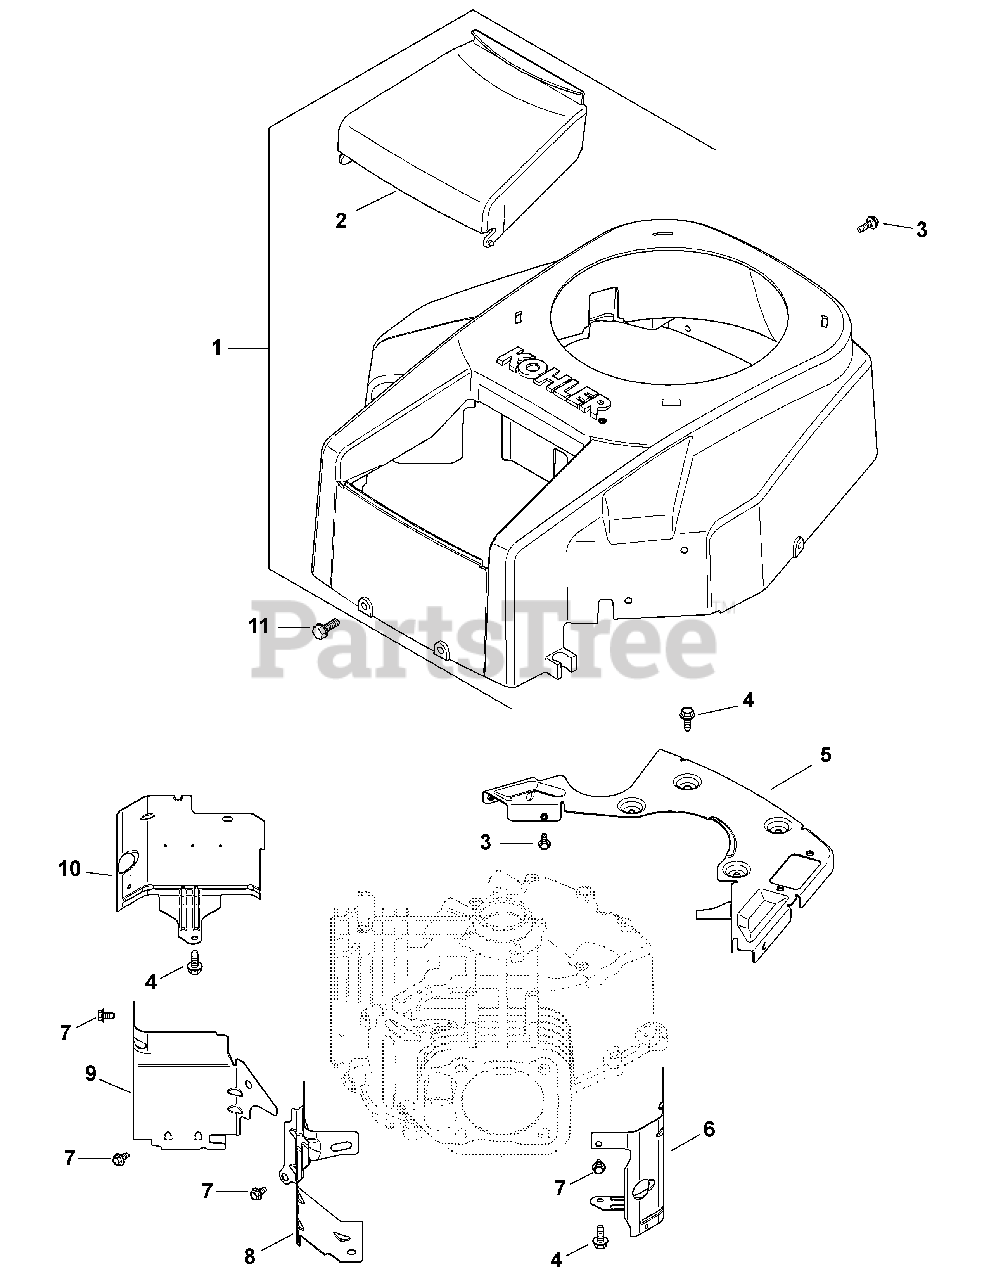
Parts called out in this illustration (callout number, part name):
1	Kit, Blower Hsng (Incl. Ref.2 & KH-41-037-10-S)
2	Cover, Air Cleaner
3	Screw, Flnge Thrd. Frmng M5 x 0.8x 16
4	Screw, Flnge Thrd. Frmng M6 x 1.0 x 16
5	Plate, Backing
6	Baffle, Cyl. Barrel - #2 Side
7	Screw, Flnge Thrd. Frmng M5 x 0.8x 10
8	Baffle, Valley #2 Side
9	Baffle, Valley #1 Side
10	Baffle, Cylinder Barrel - #1 Side
11	Screw, Tap, M6 x 1.7 x 18
